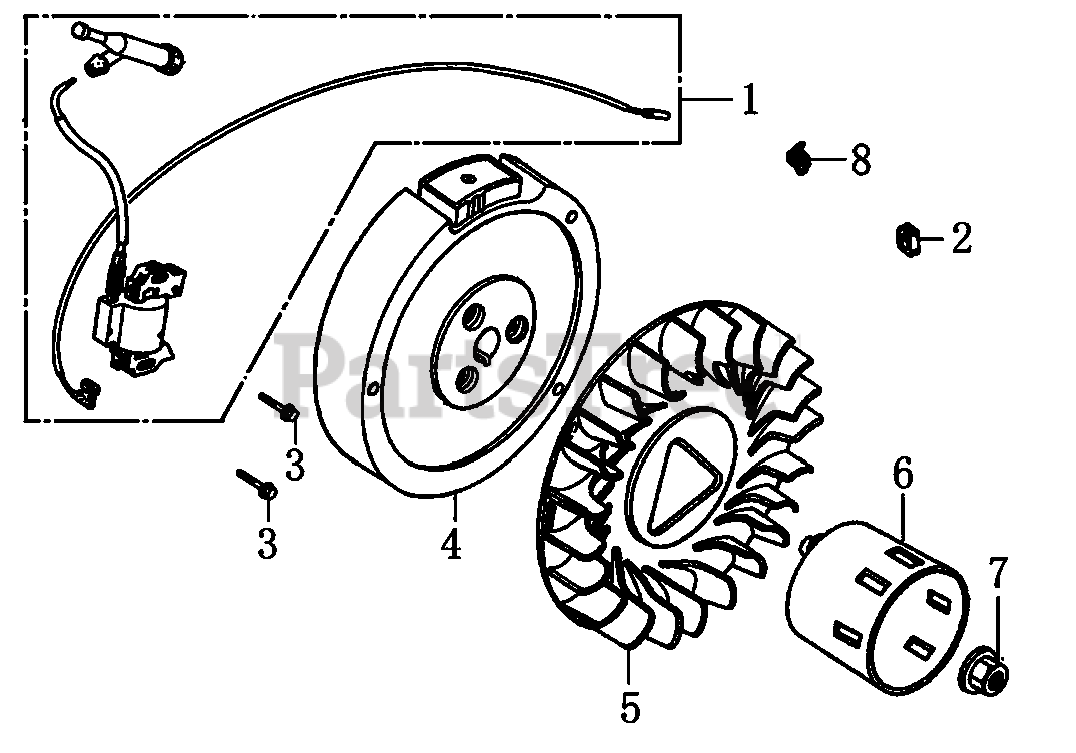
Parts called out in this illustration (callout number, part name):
1	COIL ASSY., IGNITION
2	GROMMET, CORD
3	BOLT, FLANGE,M6X25
5	FAN COOLING
6	PULLEY, STARTER
7	NUT SPECIAL,16MM
8	HOLDER, STOP SWITCH
